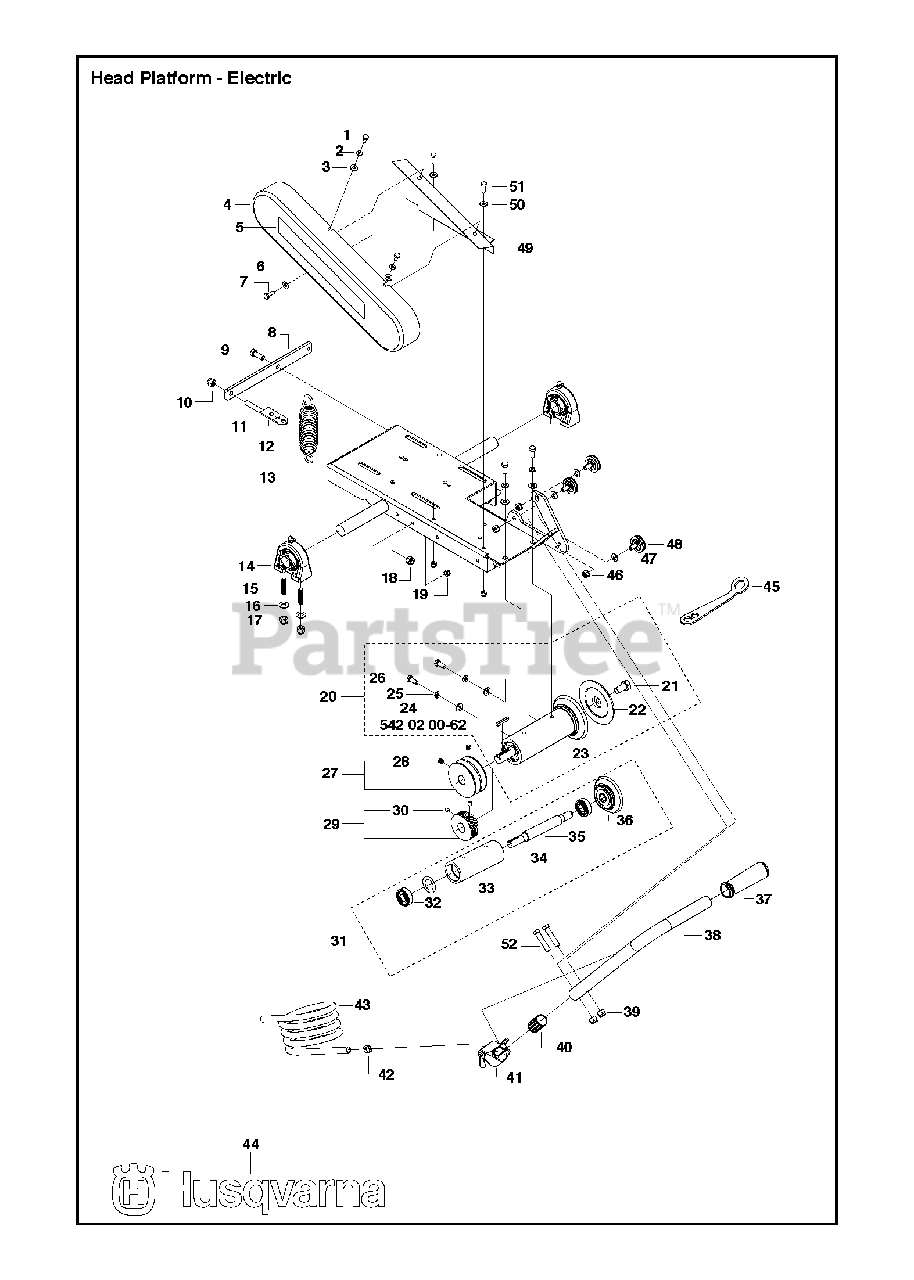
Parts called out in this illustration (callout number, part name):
1	HCS ¼-20 X ½ GR 5 ZD
3	WASHER 1/4 SAE
6	WASHER 1/4 SAE
16	WASHER
17	NUT
18	NUT
19	NUT
24	WASHER
25	WASHER
47	WASHER
48	FS700/2/900/2 WHEEL SUR/BEARIN
50	WASHER 1/4 SAE
